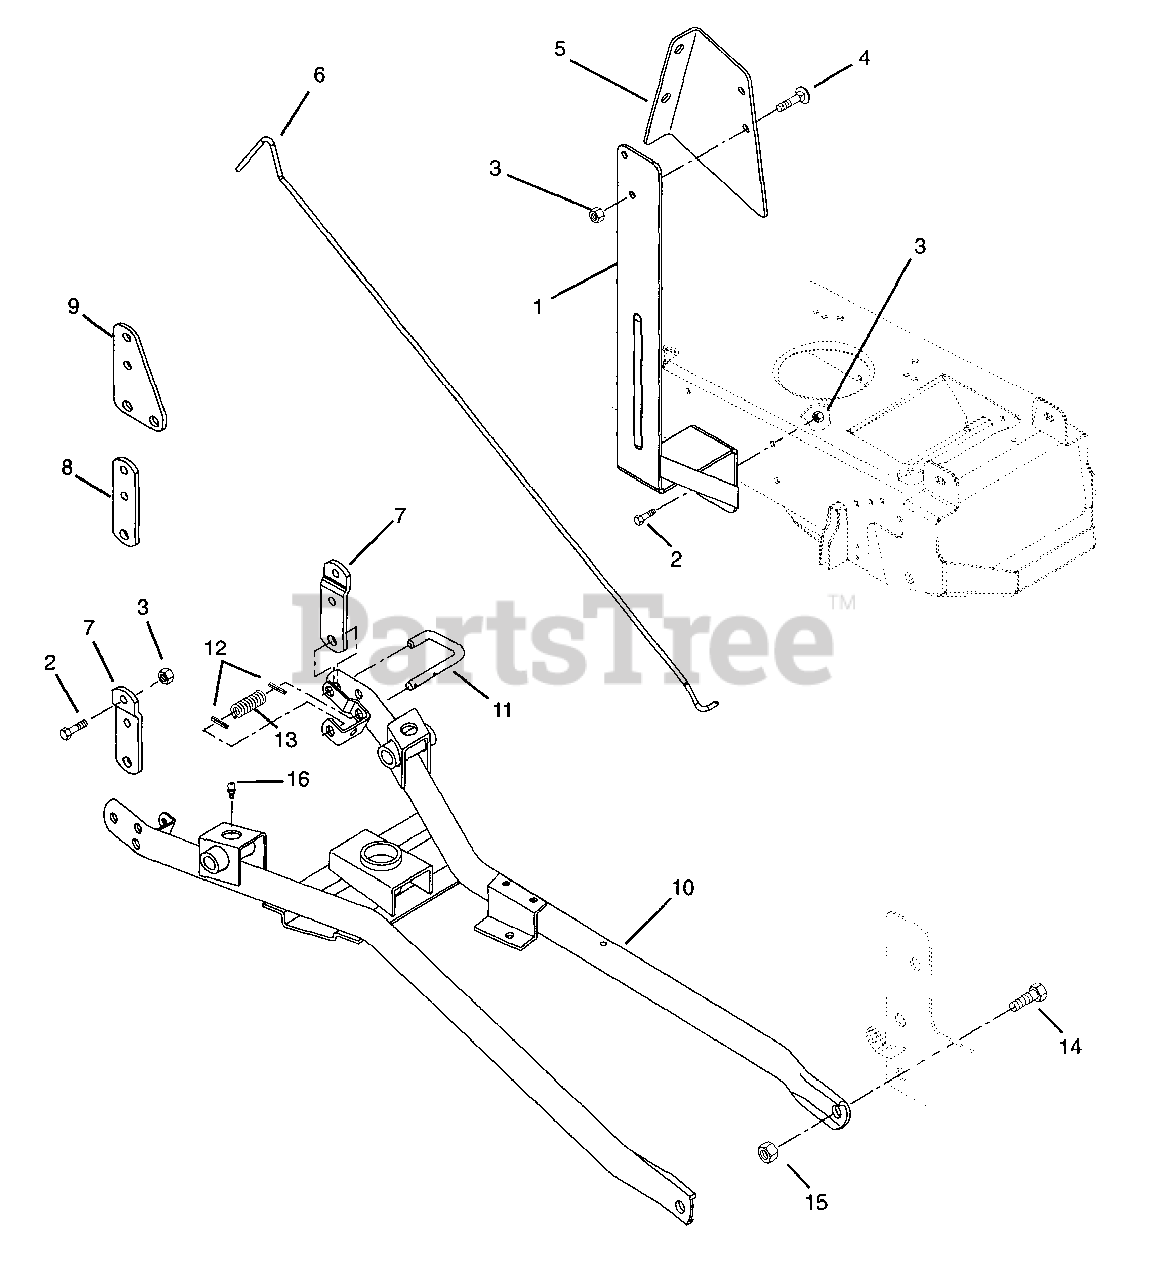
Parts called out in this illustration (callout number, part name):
1	Support-Control Bracket
2	Bolt-Hex .38-16 x .75 Grade 5
2	Bolt-Hex .38-16 x 1.00 Grade 5
3	Nut-Locking Center .38-16
4	Bolt-Round Head Square Neck .38-16 x .75
5	Control Bracket
6	Rod-Control
7	Bracket-Hanger
8	Hanger Bracket
9	Hanger Bracket
10	Carriage Frame
11	Latch Pin
12	Pin-Roll .125 x .75
13	Spring-Compression .058 x .65 x 2.13
14	Bolt-Hex .62-11 x 1.50 Grade 5
15	Nut-Locking-Center .62-11
16	Fitting-Lube .25-28 x .256
